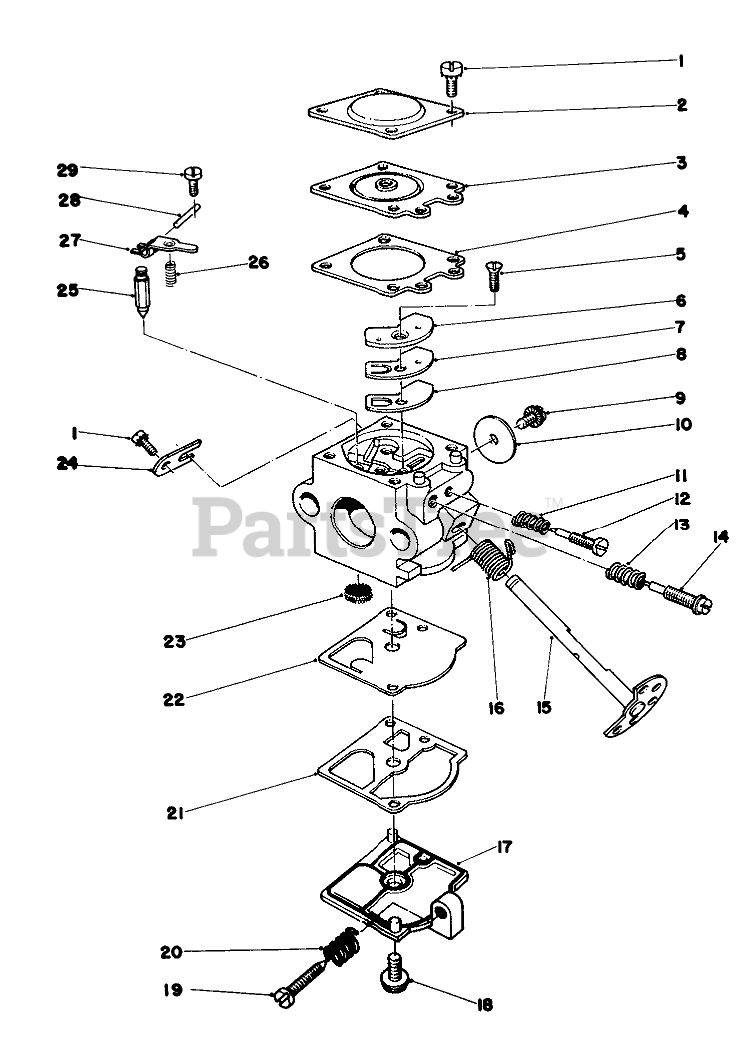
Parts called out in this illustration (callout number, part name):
1	Screw
2	Cover, Diaphragm
3	METERING DIAPHRAGM
4	Gasket, Diaphragm
5	Screw-Circuit Plate
6	Plate, Circuit
7	Diaphragm Circuit Plate
8	Gasket-Circuit Plate
9	Screw
10	Valve Throttle
11	Spring, Needle
12	Needle, Idle
13	Spring, HS Needle
14	HIGH SPEED NEEDLE
15	Shaft, Throttle
16	Spring, Throttle Return
17	Cover, Fuel Pump
18	Screw
19	Screw, Idle Adjustment
20	Spring, Idle Screw
21	PUMP GASKET
22	Diaphragm Fuel Pump
23	Screen Inlet
24	Clip Throttle Shaft
25	INLET NEEDLE VALVE
26	Spring, Lever
27	Lever Metering
28	Metering Lever Pin
29	Screw-Metering Pin
